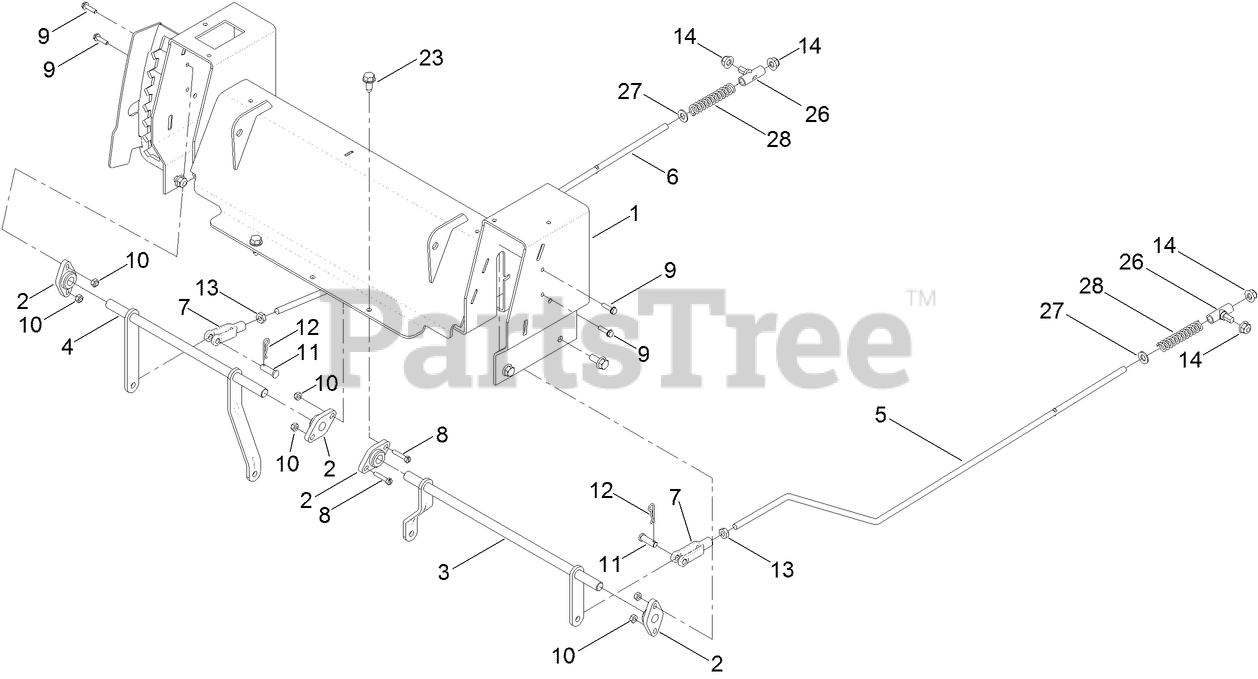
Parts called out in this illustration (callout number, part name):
1	BOX-CONTROL, WIDE
2	BEARING-FLANGE
3	BELLCRANK-LH
4	BELLCRANK-RH
5	ROD-HYDRO, LH
6	ROD-HYDRO, RH
7	YOKE-ADJUSTABLE
9	SCREW-HWH
10	NUT-LOCK, NI
11	PIN-CLEVIS
12	PIN-COTTER
13	NUT-JAM
13	SCREW-HHF
14	NUT-HF, NI
23	SCREW-HWHTF
26	MOUNT-ROD, HYDRO
27	WASHER-PLAIN
28	SPRING-RETURN, NEUTRAL
